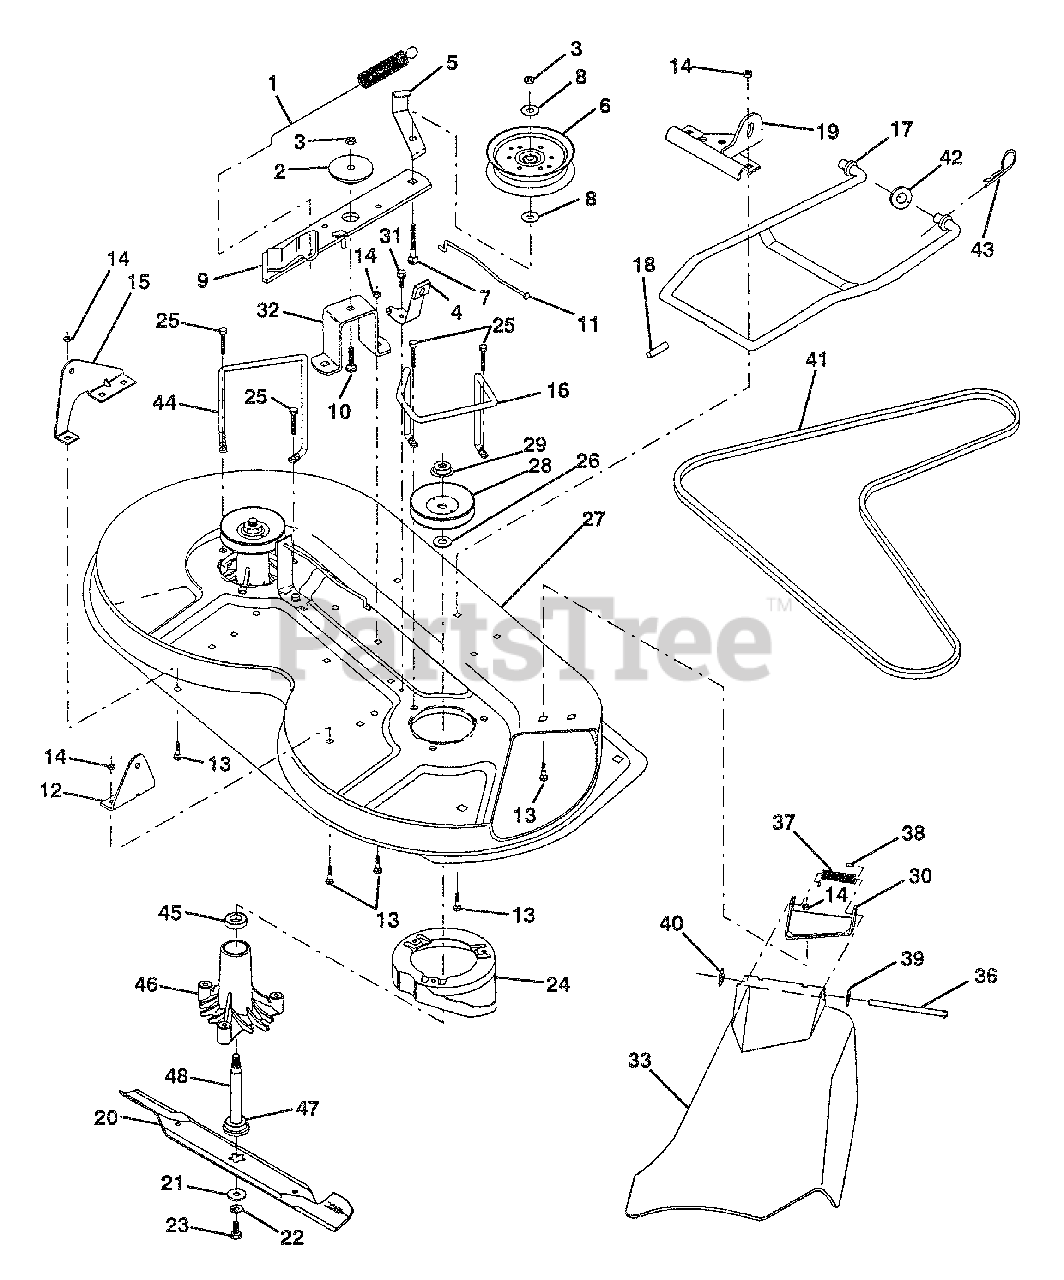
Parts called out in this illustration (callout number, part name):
1	Spring, Mower Clutch
2	Spacer, Retainer
3	Nut, Crownlock
4	Brake Asm.
5	Guide, Belt Idler
6	Pulley, Flat Idler
7	Bolt, Carr. 3/8-16 x 1-3/4 Gr. 5
8	Washer 13/21 x 7/8 x 10 Ga.
9	Arm Asm., Idler Mower
10	Bolt, Carriage 3/8-16 x 1
11	Rod, Brake
12	Bracket, Lift R.H. Rear
13	Bolt, Carriage 5/16-18 x 5/8
14	Nut, Crownlock 5/16-18
15	Bracket, Lift L.H. Rear
16	Keeper, R.H.
17	Link, Asm. Mower Stabilizer
18	Pin, Drive
19	Bracket, Asm. Front
20	Blade
21	Washer, Hard
22	Washer, Lock 3/8
23	Bolt 3/8-24 x 1-1/4 Gr. 8
24	Stripper
25	Bolt 5/16-18 x 1-1/4
26	Washer .150 Thk.
27	Deck Assembly
28	Pulley, Mandrell
29	Nut, Flangelock 9/16
30	Bracket, Asm. Deflector
31	Screw, Hex Wsh. Thdrol. 5/16-18 x 1 /2
32	Arm, Support Idler Mower
33	Deflector
36	Rod, Hinge
37	Spring, Torsion Deflector
38	Cap, Sleeve
39	Washer 11/32 x 5/8 x 16 Ga.
42	Washer 11/32 x 5/8 16 Ga.
43	Retainer, Spring
44	Keeper, L.H.
46	Housing Mandrel Vented
48	Shaft, Mandrel
